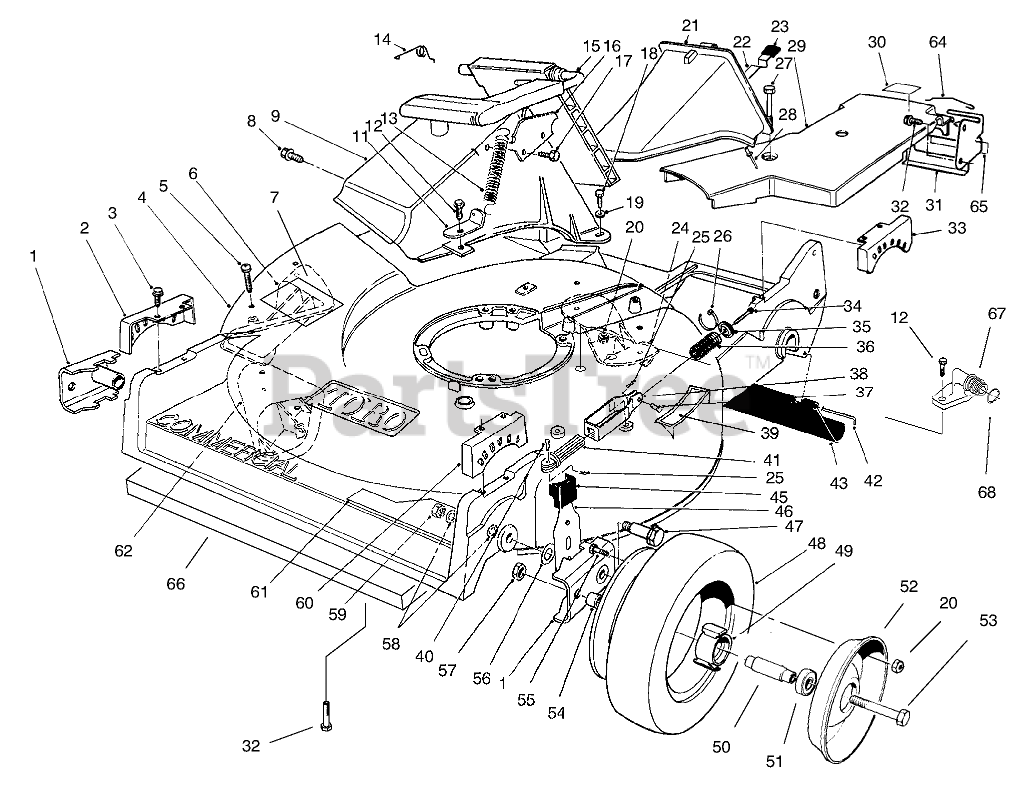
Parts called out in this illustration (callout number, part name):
1	ARM-PIVOT, FRONT
2	QUADRANT-FRONT, RH
3	SCREW-HWHTF
4	Housing-Commercial (Incl. Ref. #5-7, 12, 24, 32, 62, & 66-68 pg. 1-2)(Incl. Ref. #28 pg. 4)
5	SCREW-PPH
6	KICKER-RH
7	DECAL-DANGER
8	SCREW AND WASHER ASM
9	TUNNEL-DISCHARGE
11	BRACKET-SPRING
12	SCREW-HWH
13	SPRING-DOOR
14	RETAINER-DOOR
15	DOOR ASSEMBLY
16	DOOR LATCH PLATE
17	SCREW-PLASTITE
18	SCREW-HH
19	WASHER-FLAT
20	NUT-LOCK, NI
21	Plug-Discharge (Incl. Ref. #22, 23, & 28)
22	LATCH-PLUG, DISCHARGE
23	GRIP-LATCH
24	KICKER-REAR
25	PIN-COTTER
26	TIE-CABLE
27	SCREW-HHFTF
28	RIVET-HEAD, FLAT
29	BELT COVER (MACHINED)
30	DECAL-GREASE
31	BRACKET-ADJUSTMENT, TRACTION
32	SCREW-HWHTF
33	QUADRANT-REAR, LH
34	SCREW-HWHTF
35	RETAINER-SPRING
36	SPRING
37	PIN-CABLE
38	Bracket-Spring
39	DECAL - STEP PAD INT'L
40	PIN-SPRING
41	GUIDE-SPRING
42	ROD-SHIELD
43	SHIELD-TRAILING
45	KNOB-ARM
46	FRONT SPRING ARM ASM
47	BOLT-WHEEL
49	HUB-BEARING
50	SPACER-BEARING
51	BEARING-WHEEL
52	Wheel-Half
53	SCREW-HH
54	SPACER-WHEEL
55	SCREW-HH
56	WASHER-THRUST
57	NUT-LOCK, CONE
58	WASHER
59	NUT-LOCK
60	QUADRANT-FRONT, LH
61	DECAL - DECK
62	KICKER-FRONT
64	RETAINER-CABLE
65	DECAL-POSITION, GEAR
66	Shield-front
67	FITTING-WASHOUT
68	O-RING
